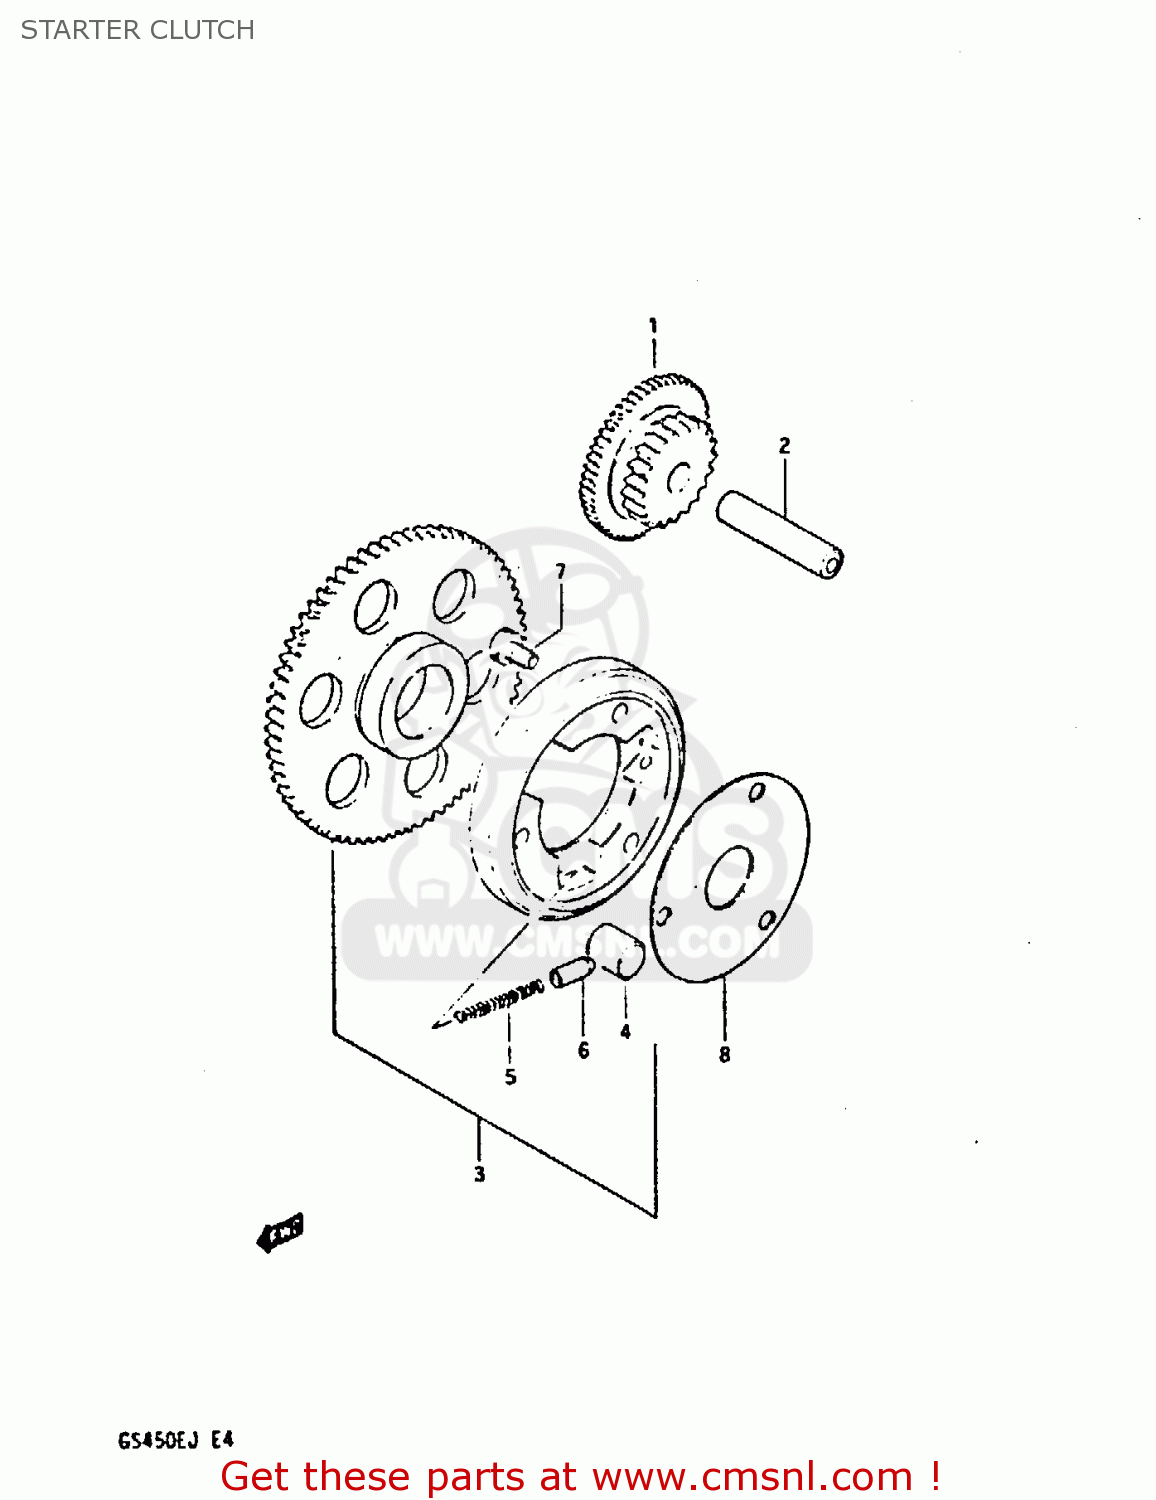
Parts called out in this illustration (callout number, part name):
1	GEAR,STARTER IDLE
2	PIN(7.4X13X56)
3	CLUTCH SET,STARTER
4	ROLLER(15X13)
5	SPRING
6	PIECE,PUSH
7	BOLT
8	SHIM,STARTER CLUTCH HUB
